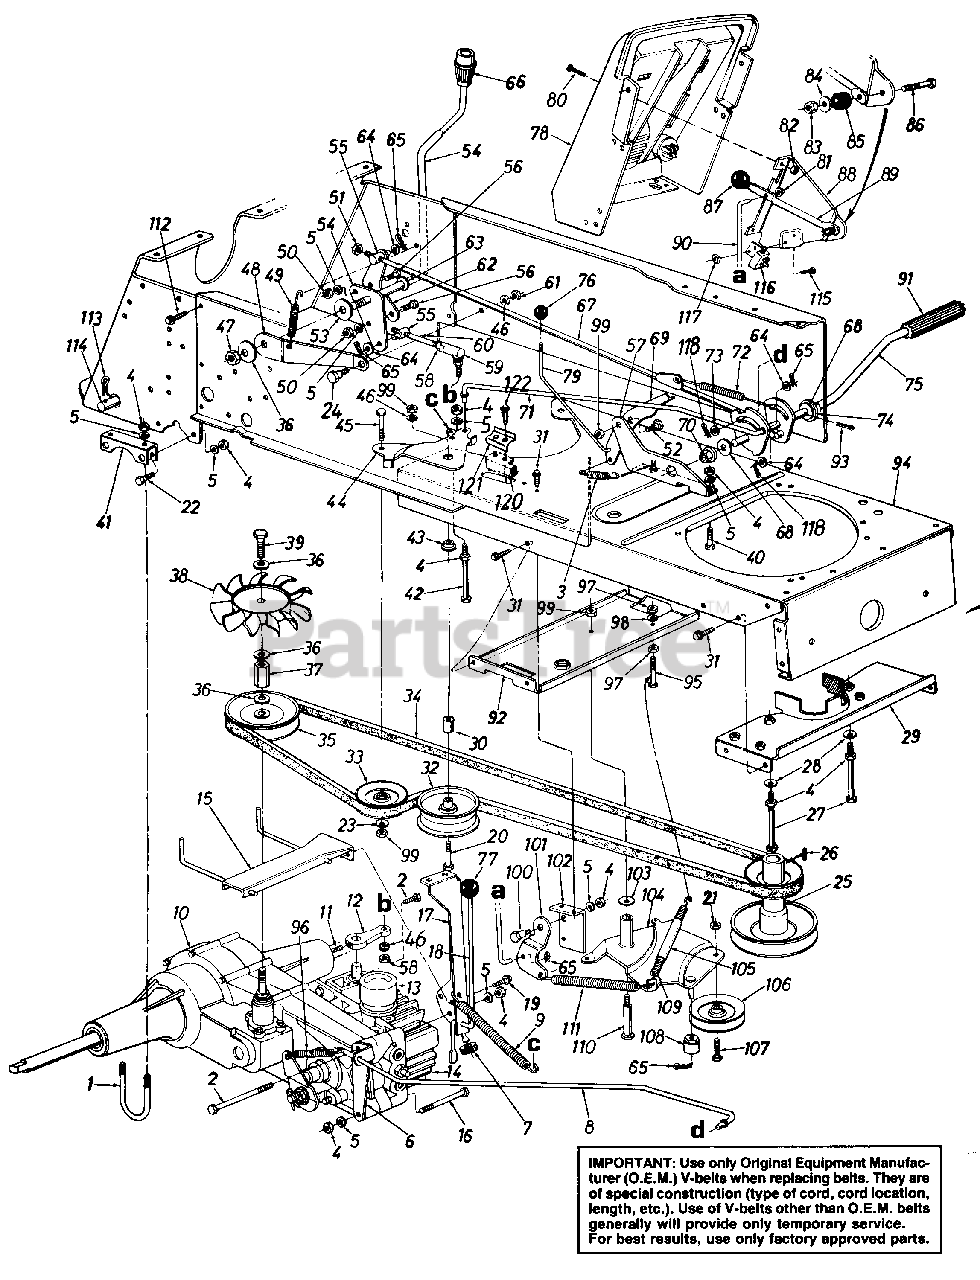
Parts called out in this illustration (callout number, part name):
1	U-Bolt 5/16-18 x 3.25" Lg.
2	Hex Patch Bolt 5/16-18 x 4.5" Lg. (Gr. 5)
3	Ext. Spring .5" O.D. x 1.55"
4	Hex Nut 5/16-18 Thd.
5	L-Wash. 5/16" I.D.
6	Brake Rod Guide Brkt.
7	Rubber Wash. .33" I.D. x .87"
9	Ext. Spring .62" O.D. x 6.12" Lg.
11	Set Screw 5/16-24 x .38" Lg.
12	Pintle Shift Lever
13	Reservoir
14	Hydrostatic Pump
15	Belt Guard Ass'y.
16	Hex Bolt 5/16-18 x 4.5" Lg. Gr. 5
17	Transaxle Torque Bracket
18	Transaxle Control Rod
19	Hex Wash. Hd. B-Tap Scr. 5/1 6-1 8
20	Hex Bolt 3/8-16 x 2.75" Lg.
21	Hex Cent. Lock Nut 3/8-16 Thd.
22	Hex Bolt 5/16-18 x .75" Lg. Gr. 5
23	Fl-Wash. .385" I.D. x .87" O.D.
24	Shld. Bolt .5" Dia. x .212"
25	Engine Pulley
26	Sq. Key 1/4 x 1.5" Lg.
27	Hex Bolt 5/16-18 x 5.25" Lg.
28	Bell-Wash. .345" I.D. x .88" O.D.
29	Belt Keeper Brkt. Ass'y.
30	Spacer .375" I.D. x .75" Lg.
31	Hex Wash. Hd. TT-Tap Scr. 1/4-20 x .5" Lg.
32	Fl-ldler Pulley 3.25" Dia.
33	V-Belt Idler
34	V-Belt
35	Transmission Pulley 4.25" O.D.
36	Bell-Wash. .56" I.D. x 1.5"
37	Fan Adapter Nut 9/16-18 Thd.
39	Hex Bolt 9/16-18 x .5" Lg.
40	Hex Bolt 5/16-18 x .75" Lg.
41	Transaxle Mtg. Bracket
42	Hex Bolt 5/16-18 x 2.75" Lg.
43	Shld. Spacer .625" I.D.
44	Clutch Idler Bracket
45	Hex Bolt 3/8-16 x 1.5" Lg.
46	L-Wash. 3/8" I.D.
47	Hex Jam Nut 1/2-20 Thd.
48	Speed Control Rod Torque Brkt.
49	Ext. Spring 2.5" Lg.
50	Hex Nut 5/16-24 Thd.
51	Hex Jam Nut 3/8-24 Thd.
52	Shld. Bolt .50n Dia. x .170"
53	Fiber Washer .54" I.D. x 1.75"
54	Speed Control Handle Ass'y.
55	Ferrule 3/8-24 Thd.
56	Hex Bolt 5/16-24 x .62" Lg.
57	Foot Pedal Mtg. Brkt.
58	Hex Nut 3/8-24 Thd.
59	Ball Joint Ass'y.
60	Control Rod 3/8-24 x 3.75" Lg.
61	Hex Nut 3/8-16 Thd.
62	Speed Selector Handle Brkt.
63	Fl-Wash. .531" I.D. x 1.25n O.D.
64	Fl-Wash. .385" I.D. x .62" O.D.
65	Internal Cotter Pin
67	Neutral Return Rod
68	Fl-Wash. .64" I.D. x 1.24" O.D.
69	Parking Brake Lock Brkt.
70	Hex Flange Brg. 634n Dia.
71	Clutch Idler Rod
72	Extension Spring 8" Lg.
73	Fl-Wash. .344" I.D. x .62" O.D.
74	Flange Bearing w/Flats
75	Foot Pedal Ass'y.
76	Ball Knob Brake
77	Ball Knob 1/4-20 Thd.
78	Dash Panel Ass'y.
79	Parking Brake Link
80	Truss Mach. Scr. 1/4-20 x .5" Lg.
81	Push Nut 1/4" O.D. Rod
82	Hex Sems Nut 1/4-20 Thd.
83	Hex L-Nut 1/4-20 Thd.
84	Fl-Wash. .281" I.D. x .73" O.D.
85	Rubber Wash. .33" I.D. x .87"
86	Hex Bolt 1/4-20 x 1.25" Lg.
87	Knob-Blade Clutch
88	Deck Clutch Cont. Brkt.
89	Blade Clutch Lever
90	Deck Control Rod
91	Foot Pad
92	Deck Idler Support Brkt.
93	Cotter Pin 1/8" Dia.
94	Lower Frame
95	Hex Bolt 1/4-20 x 2" Lg.
96	Ext. Spring 3.675" Lg.
97	Hex Nut 1/4-20 Thd.
98	L-Wash. 1/4n l.D.
99	Hex Cent. L-Nut 3/8-16 Thd.
100	Shld. Bolt .437" Dia. x .162"
101	Deck Control Pivot Brkt.
102	Parking Brake Mtg. Brkt.
103	Bell-Wash. 380n l.D. x .88" O.D.
104	Idler Brkt. Deck Ass'y.
105	Convoluted Conduit 4" Lg.
106	V-Belt Idler
107	Hex Bolt 3/8-24 x 1.5" Lg.
108	Spacer
109	Ext. Spring 6.87" Lg.
110	Shld. Bolt 498" Dia. x 2.05"
111	Ext. Spring 6.12" Lg.
112	Hex Wash. AB-Tap Scr. 5/16 x ,7sn Lg.
113	Hitch Pin Clip
115	Truss Mach. Scr. #10-24 X ,5n
116	Safety Switch
117	Hex Nut #10-24 Thd.
118	Cotter Pin 3132" Dia. x 1.0" Lg.
120	Safety Switch
121	Switch Plate
122	Torx Mach. B-Tap Scr.
